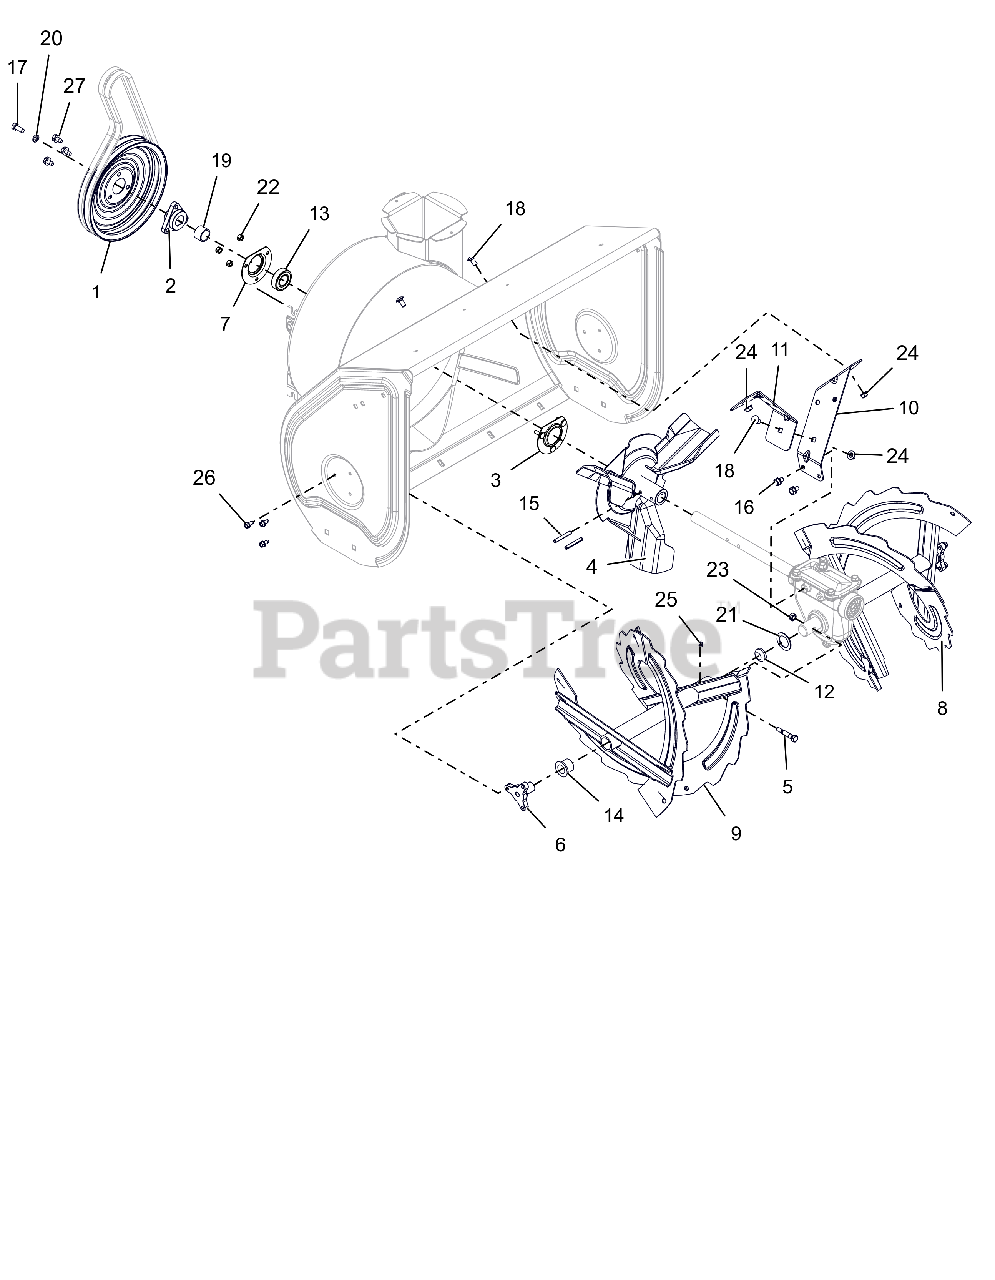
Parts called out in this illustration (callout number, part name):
1	PULLEY, SPIN FORM DUAL GROOVE
2	PULLEY HUB, D-BORE .87 DELUXE
3	BEARING FLANGE
4	IMPELLER, 3 BLADE-14"
5	BOLT, SHEAR - DELUXE
6	SUPPORT, RAKE BUSHING
7	BEARING FLANGE
8	RAKE, LH W/ZERK - 28"
9	RAKE, RH W/ZERK - 28"
10	BRACKET, GEARCASE SUPPORT - LH
11	BRACKET, GEARCASE SUPPORT - RH
12	PLUG, RAKE TUBE
13	BRG-BALL .876X1.75X.50 RSTFP
14	BSHG-FLG, NY.778 ID X 1.018 OD
15	PIN-ROLL .250X1.75
16	BOLT, SEMS .31-18X.50 GR5 YWZC
17	BLT-HEX .31-24X.75 YWZC GR5
18	BLT-RDHDSQSHNK.31-18X.62 YZ-LK
19	BSHG,SPCR .895X1.065X.693
20	WSHR-LK .312X.097 HVY YWZC
21	WSHR-FL-STL 1.010X1.505X.062YZ
22	@NUT-LK-CTR .25-20 YWZC
23	@NUT-LK-CTR .31-18 YWZC
24	@NUT-LK-TOP-FLG .31-18 YWZC
25	ZERK,FITTING .25X.125 DRIVE IN
26	SCR-TAP .25-20X.50 HWH TR YWZ
27	@SCR-TAP .31-18X.50 HWH TR YWZ
